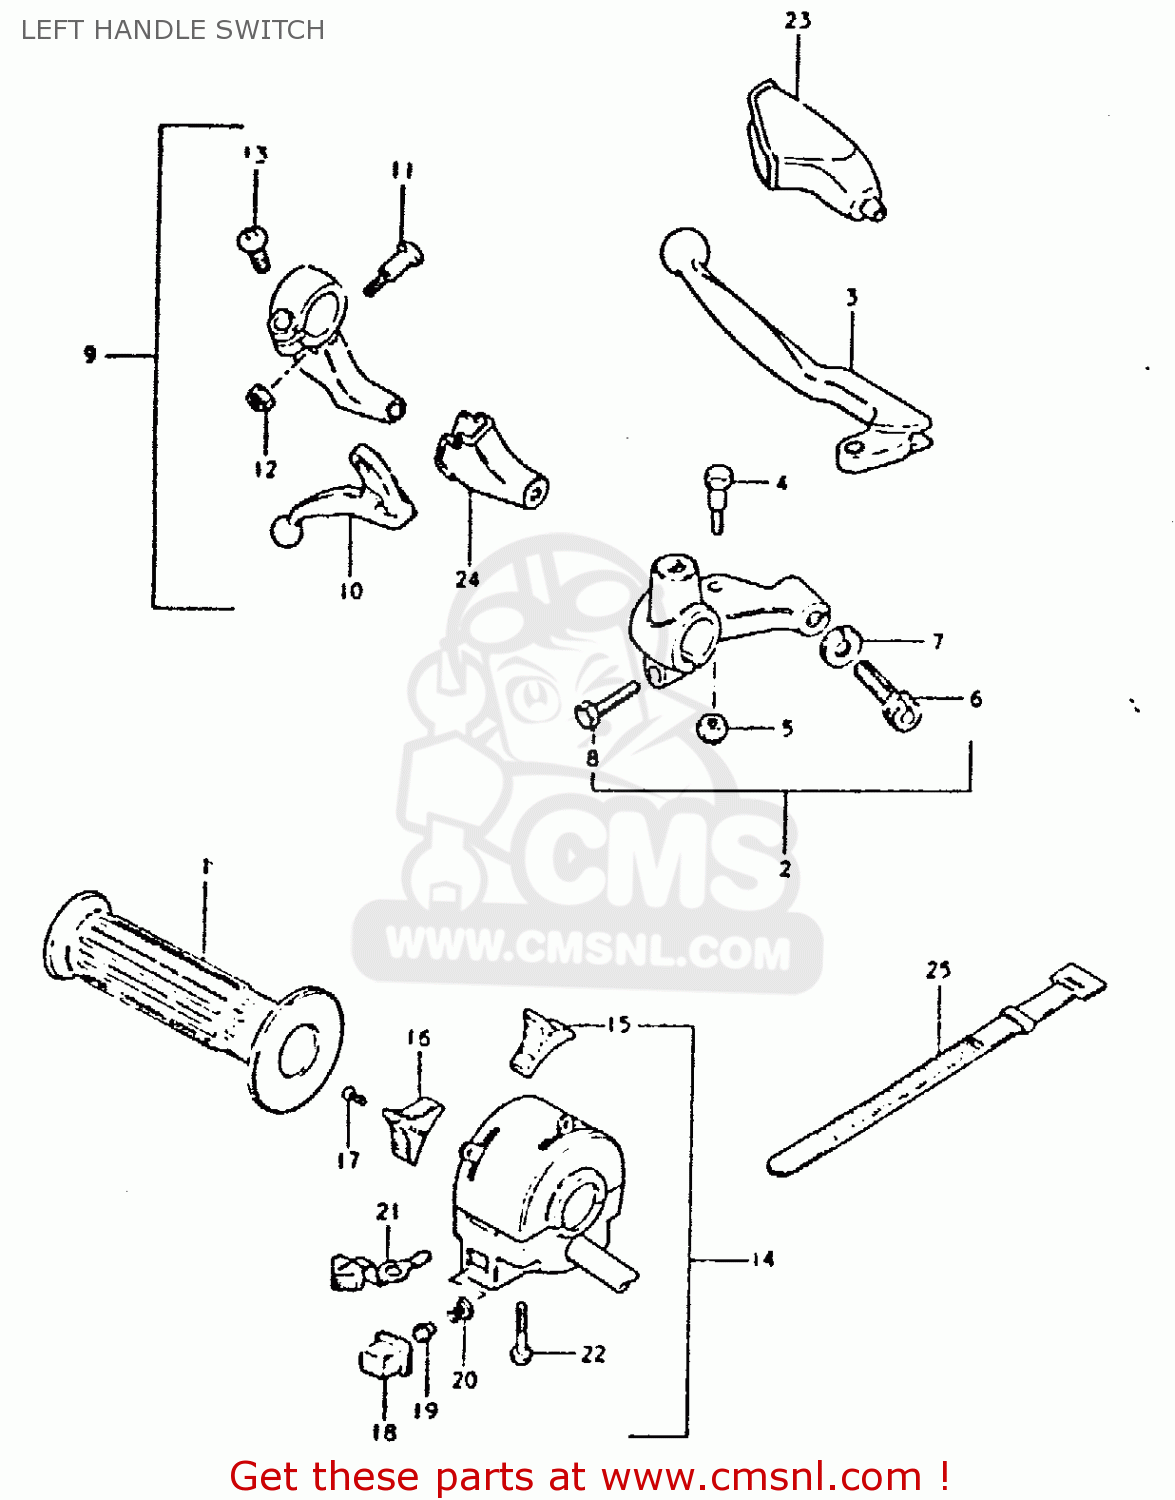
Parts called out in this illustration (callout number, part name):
1	GRIP,L
2	LEVER ASSY,CLUTCH
3	LEVER,CLUTCH
4	BOLT,LEVER
5	NUT 6MM
6	ADJUSTER,CABLE
7	NUT,CABLE ADJUSTER
8	BOLT
9	LEVER ASSEMBLY,DECOMPRESSION
10	LEVER,DECOMPRESSION
11	BOLT,LEVER
12	NUT,LEVER BOLT
13	SCREW
14	SWITCH ASSY, HANDLE LH
15	KNOB,LIGHTING SWITCH
16	KNOB,DIMMER SWITCH
17	SCREW
18	BUTTON,HORN
19	CONTACT
20	SPRING
21	KNOB,TURNSIGNAL
22	SCREW
23	COVER,CLUTCH LEVER
24	COVER,DECOMP LEVER DUST
25	CLAMP(L:120)
